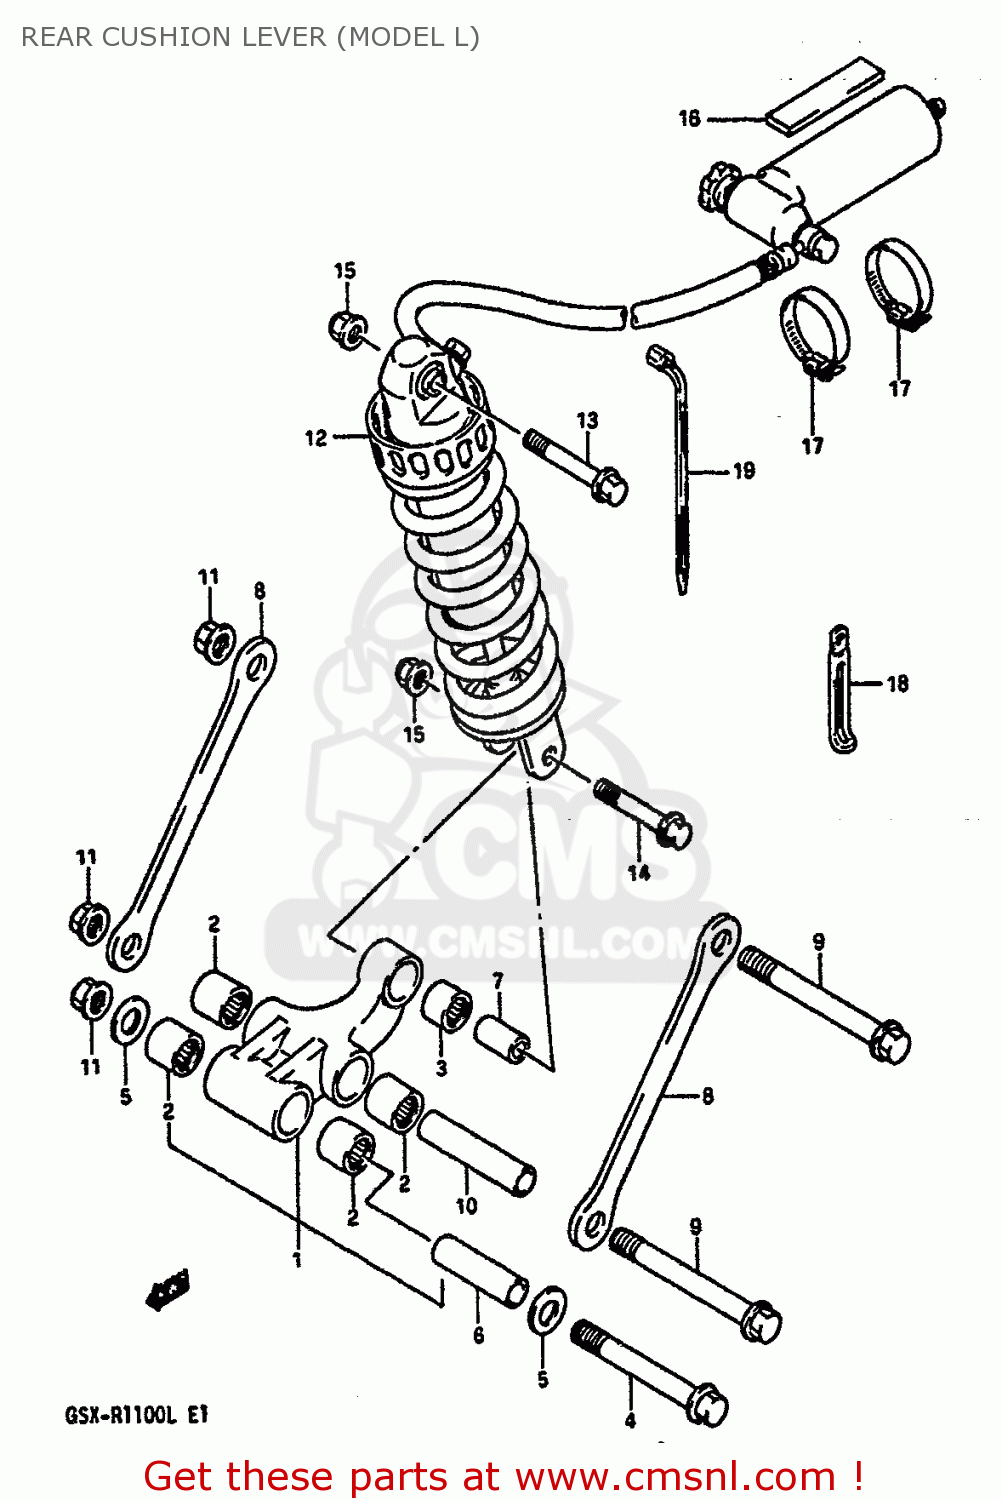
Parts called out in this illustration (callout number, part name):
1	LEVER SET,REAR CUSHION
2	BEARING(20X27X23.5)
3	BEARING(17X24X26)
4	SHAFT,RR CUSHION LEVER FR
5	WASHER
6	SPACER,RR CUSHION LEVER
7	SPACER,RR CUSHION LEVER
8	ROD,REAR CUSHION LEVER
9	SHAFT,RR CUSHION ROD
10	SPACER,RR CUSHION ROD
11	NUT
12	ABSORBER,RR SH
13	BOLT
14	BOLT(10X60)
15	NUT
16	CUSHION,RESERVOIR TANK
17	CLAMP
18	CLAMP
19	CLAMP(L:165)
21	BOLT
22	BOLT(10X60)
23	NUT
24	CUSHION,RESERVOIR TANK
25	CLAMP
26	CLAMP
